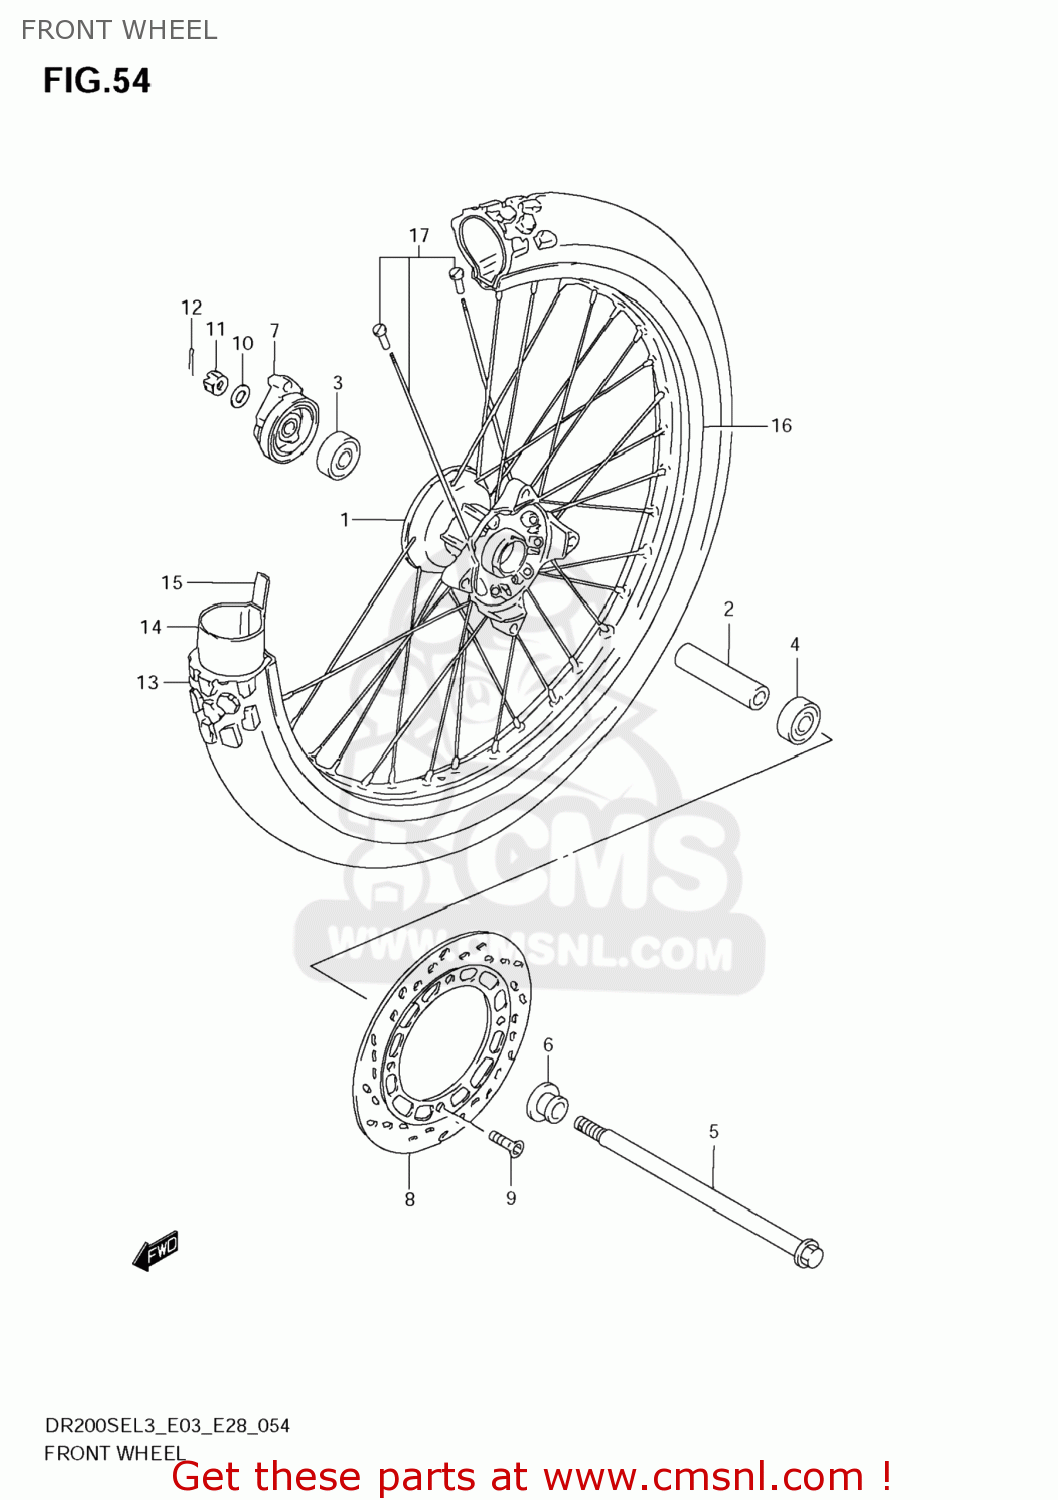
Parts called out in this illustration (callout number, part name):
1	HUB,FR WHEEL
2	SPACER(12.5X19X60.5)
3	BEARING
4	BEARING (12X32X10)
5	AXLE,FR
6	SPACER,FR AXLE
7	BOX ASSY,SPEEDOMETER GEAR
8	DISC,FR BRAKE
9	BOLT(8X20)
10	WASHER
11	NUT
12	PIN
13	TIRE,FR(70/100-21 44P)
14	TUBE ASSY,WHEEL INNER
15	PROTECTOR,WHL INR TUBE
16	RIM,FR WHEEL(21X1.60)
17	SPOKE SET,FR WHEEL
